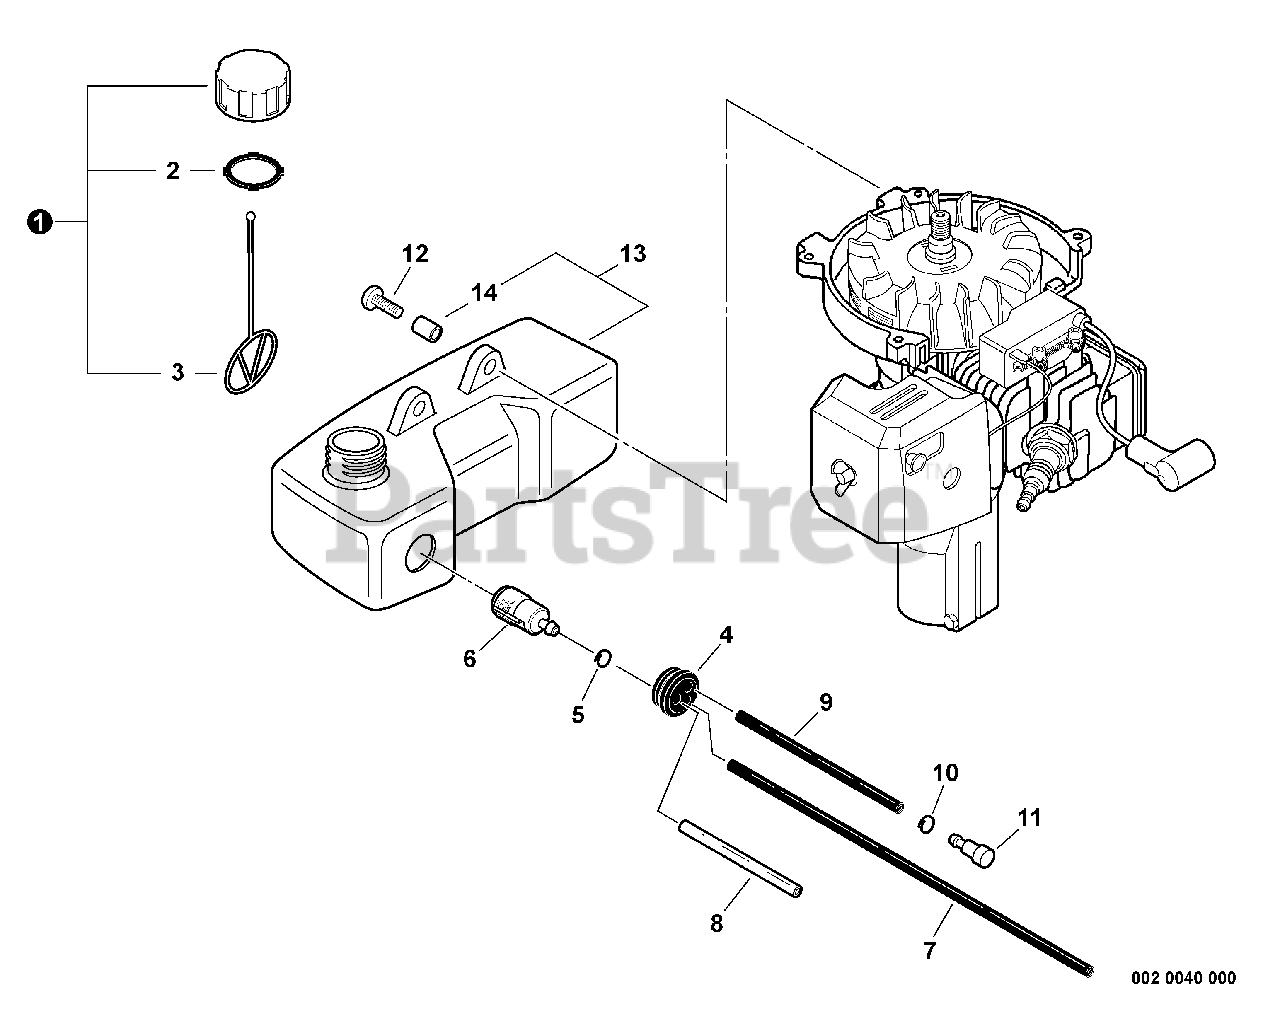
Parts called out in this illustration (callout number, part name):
1	SCREW - 5X15
2	FUEL TANK ASSY
4	GROMMET
5	CLIP - 6
6	FILTER, FUEL
7	PIPE - 3X5X210 -- BLACK
8	PIPE - 3X6X50 -- CLEAR
9	PIPE - 3X5X70 -- BLACK
10	CLIP - 5.5
11	VENT, FUEL TANK
12	CAP ASSY
13	GASKET, CAP
14	CONNECTOR, CAP
